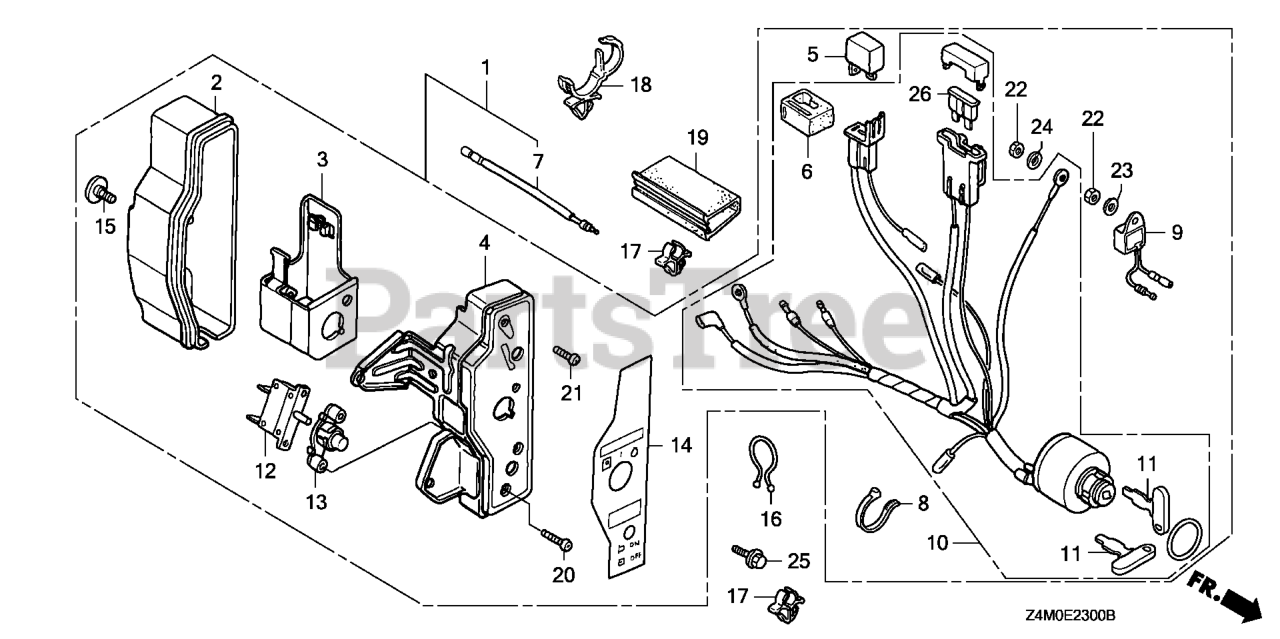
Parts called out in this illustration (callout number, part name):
1	BOX ASSY., CONTROL *NH1* (EXP-ALERT) (BLACK)
1	BOX ASSY., CONTROL *R280* (EXP-ALERT) (POWER RED)
2	CASE, CONTROL
3	BRACKET, CASE MOUNTING
4	PANEL, CONTROL *NH1* (BLACK)
4	PANEL, CONTROL *R280* (POWER RED)
5	RECTIFIER ASSY., SILICON (SHINDENGEN)
6	SUSPENSION, CONNECTOR
7	SUB-WIRE HARNESS
8	BAND
9	ALERT UNIT, OIL
10	SWITCH ASSY., COMBINATION
11	KEY
12	PROTECTOR, CIRCUIT (1.0A)
13	LENS ASSY., PROTECTOR
14	MARK, CONTROL BOX (EXTERNAL)
15	SCREW, SPECIAL (6X12)
16	CLIP, PURSE LOCK
17	CLIP, CORD
18	STRAP, WIRE HARNESS (25MM) (BLACK)
19	TUBE, FASTENER (30)
20	SCREW, PAN (3X12)
21	SCREW, PAN (4X12)
22	NUT, HEX. (4MM)
23	WASHER, PLAIN (4MM)
24	WASHER, SPRING (4MM)
25	BOLT, FLANGE (6X10)
26	FUSE, BLADE (5A)
